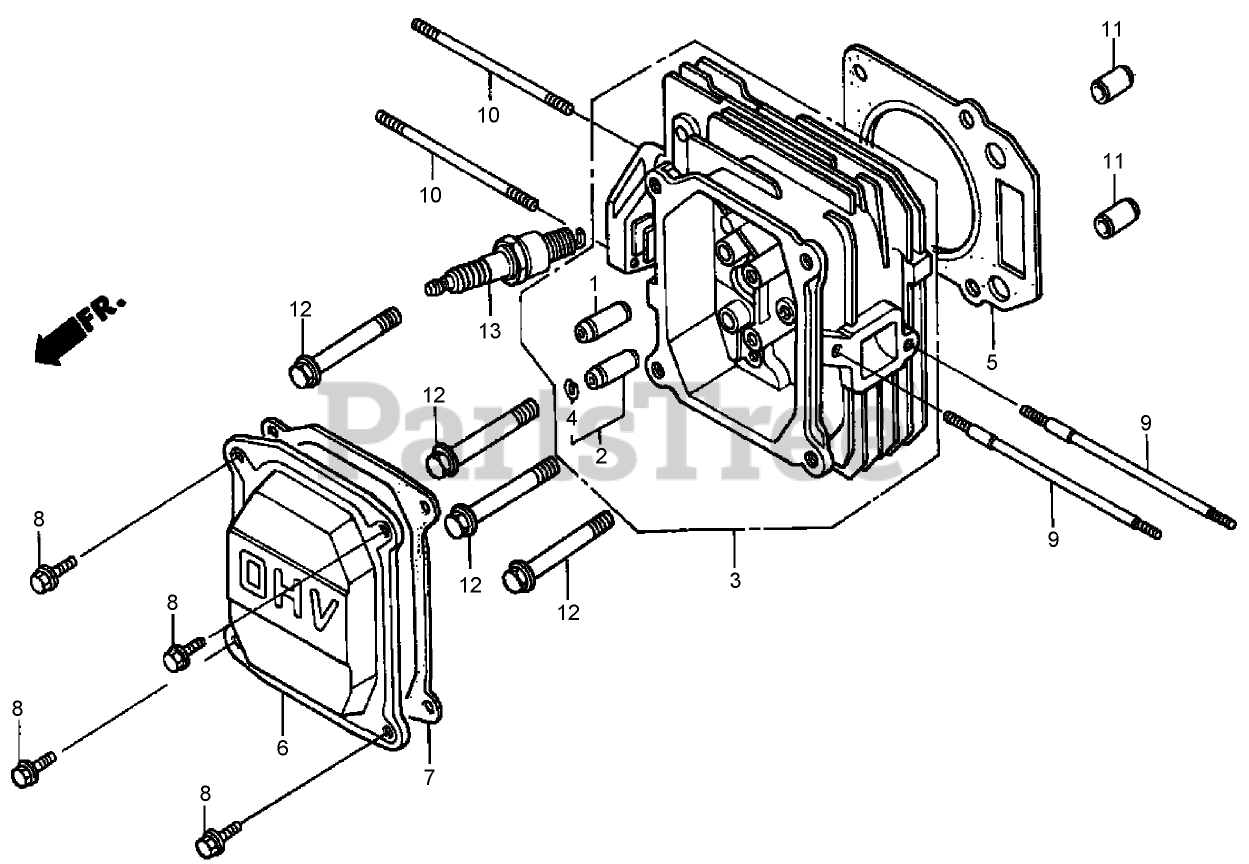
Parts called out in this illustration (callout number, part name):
1	GUIDE-VALVE (O S)
2	GUIDE-VALVE, EXHAUST (O S)
3	HEAD-CYLINDER
4	CLIP-GUIDE, VALVE
5	GASKET-HEAD, CYLINDER
6	Cover-Head
7	Gasket-COVER, Cylinder Head
8	BOLT-FLANGE (6X12) (C T200)
9	BOLT-STUD (6X109)
10	BOLT-STUD (6X85)
11	PIN-DOWEL (10X16)
12	BOLT-FLANGE (8X50)
13	SPARK PLUG (B P R4E S) (N G K)
13	SPARK PLUG (W14E P R-U) (DENSO)
13	SPARK PLUG (B P R 5E S) (N G K)
13	SPARK PLUG (W16E P R-U) (DENSO)
13	SPARK PLUG (B P R 6E S) (N G K)
13	SPARK PLUG (W20E P R-U) (DENSO)
